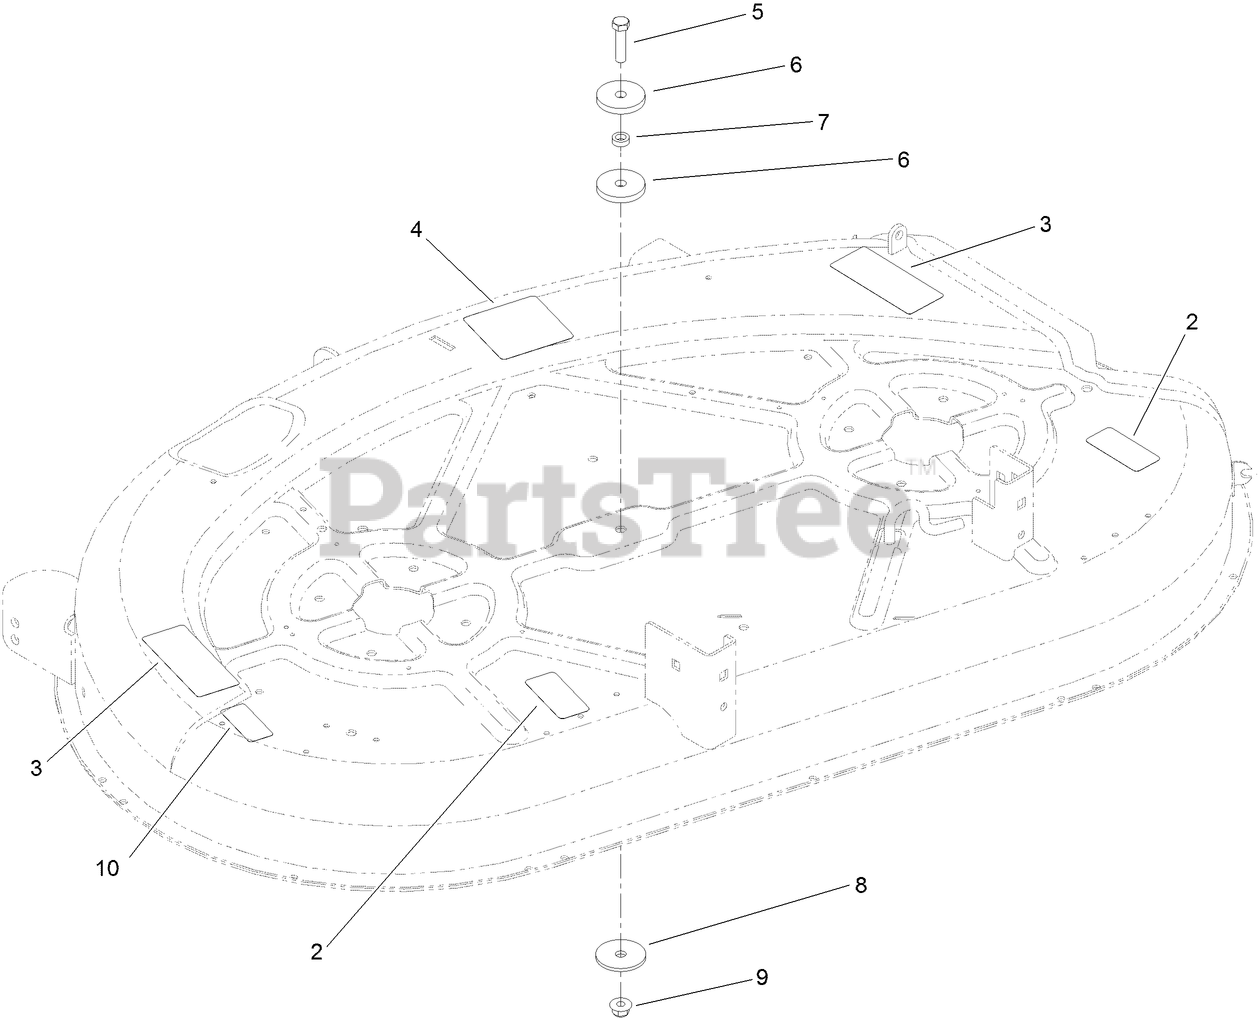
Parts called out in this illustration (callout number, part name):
2	DECAL-WARNING
3	DECAL-WARNING
4	DECAL-GUIDE, BELT
5	SCREW-HH
6	WASHER-PLAIN
7	SPACER
8	WASHER-REBOUND
9	NUT-HF, NI
10	DECAL-SERVICE DECK
